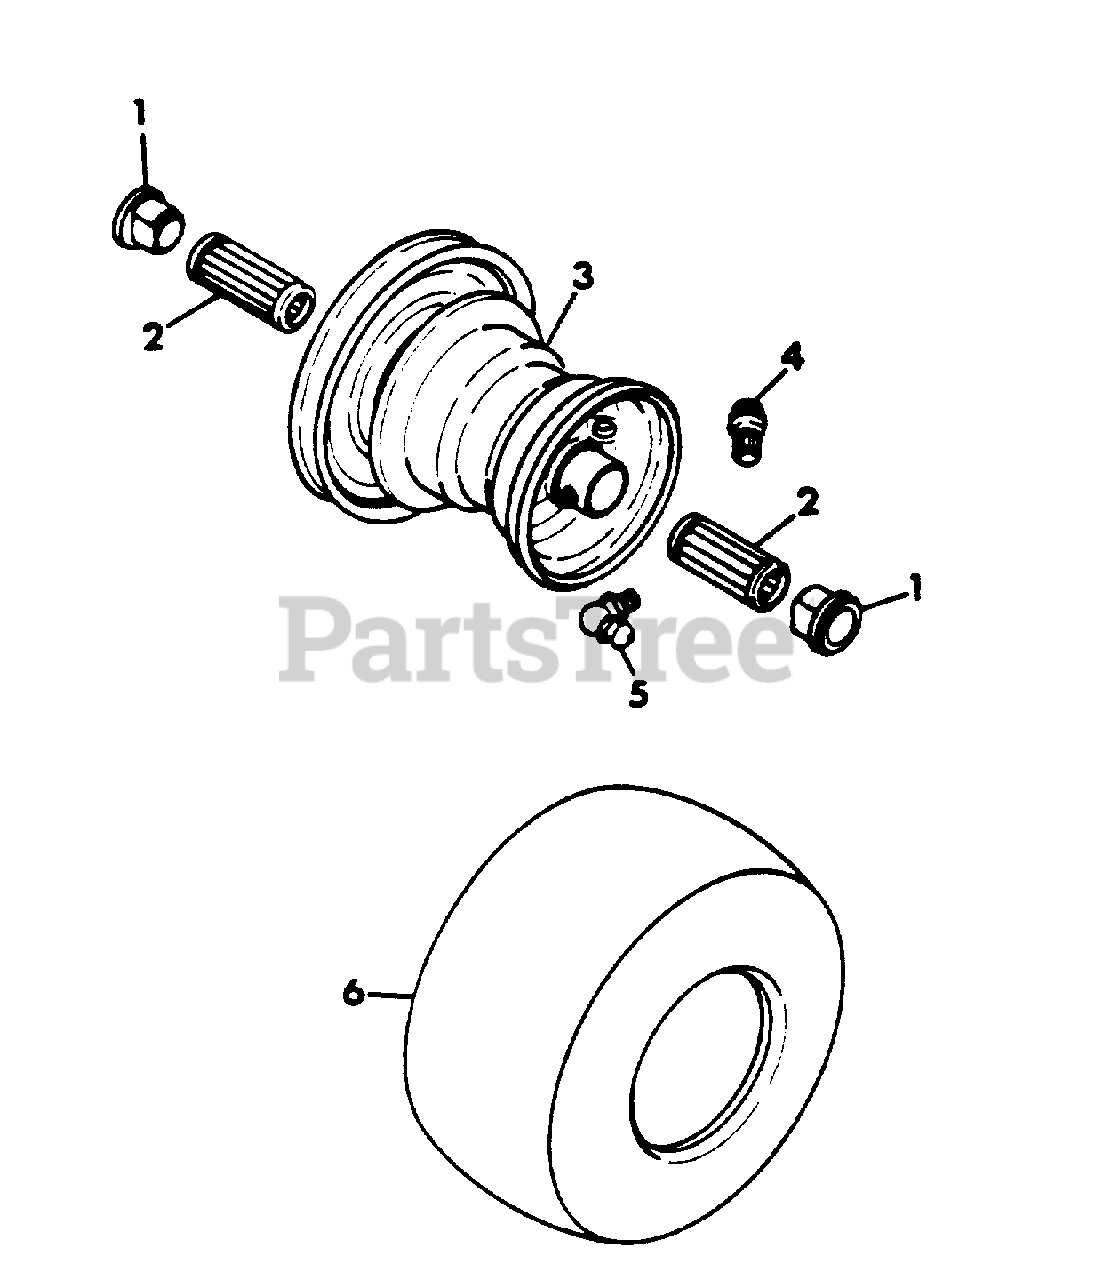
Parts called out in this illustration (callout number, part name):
1	BEARING, FLANGE
2	BEARING, 7/8X2.50
3	RIM
4	ASSEMBLY, VALVE STEM
5	FITTING, LUBE 90 DEG.
6	TIRE, 13X6.50-6
